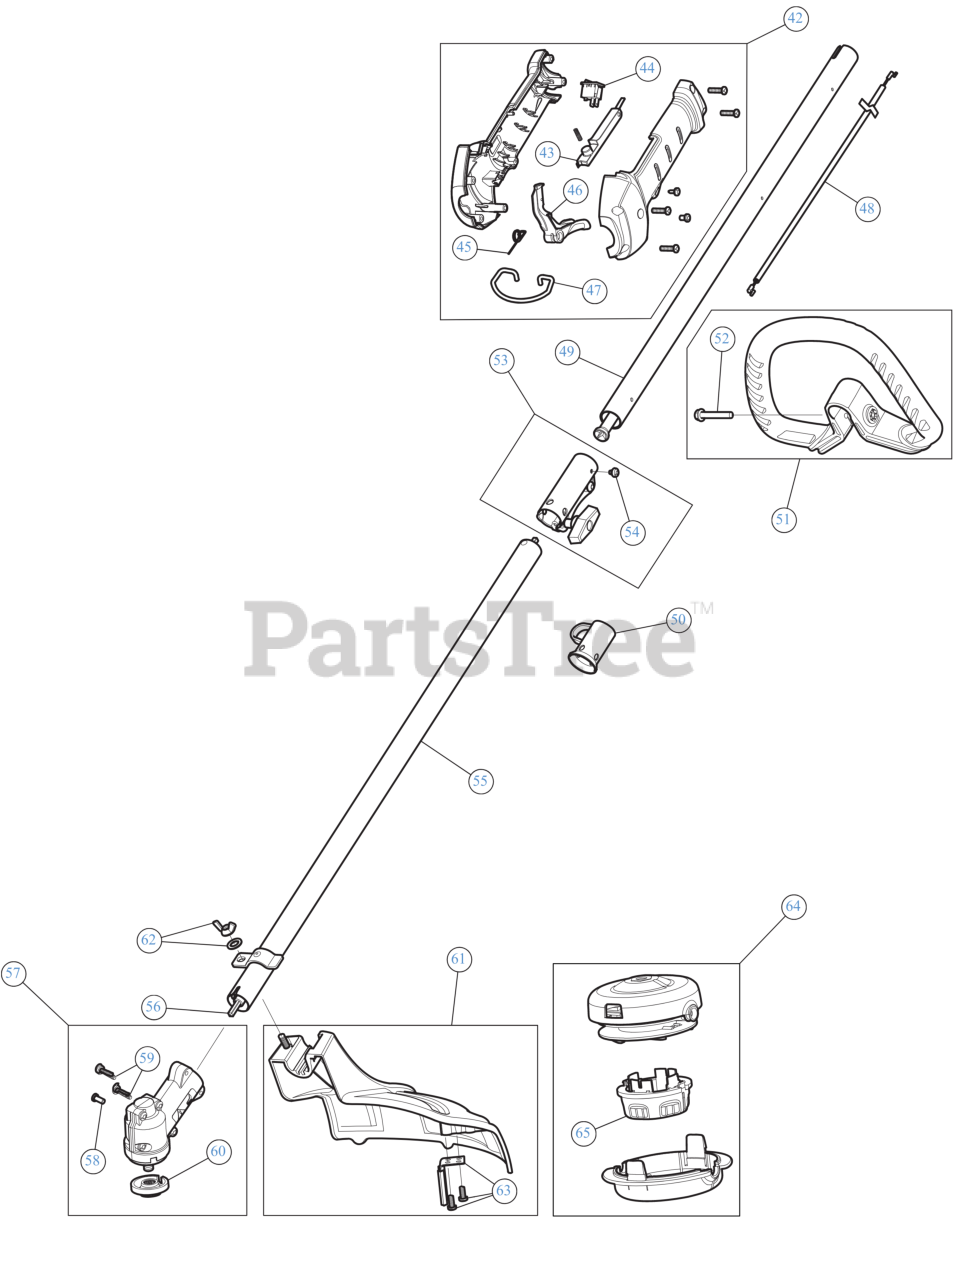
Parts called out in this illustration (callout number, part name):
42	THROTTLE GRIP ASM
43	LEVER LOCK OUT
44	SW, MOMENTARY ON/O
45	SPRING TRIG
46	THROTTLE TRIGGER
47	SHOULDER STRAP CLIP
48	THROTTLE CABLE
49	DRIVE SHAFT ASSEMBLY UP
51	HANDLE ASSEMBLY
52	BOLT 1/4-20X1 1/2
53	SPLIT BOOM COUPLER KIT
54	SCREW, 10-32X.250 TA
55	BOOM ASSEMBLY LOWER
56	FLEX SHAFT LOWER
57	GEARBOX LCBC
58	SCREW, 8-32 x .312 P
60	CUTTING HEAD SPACER
61	GUARD/BLADE ASM
62	BLADE GUARD MOUNTING HARDWARE
63	BLADE ASSEMBLY W/HDW
64	HEAD ASSEMBLY
